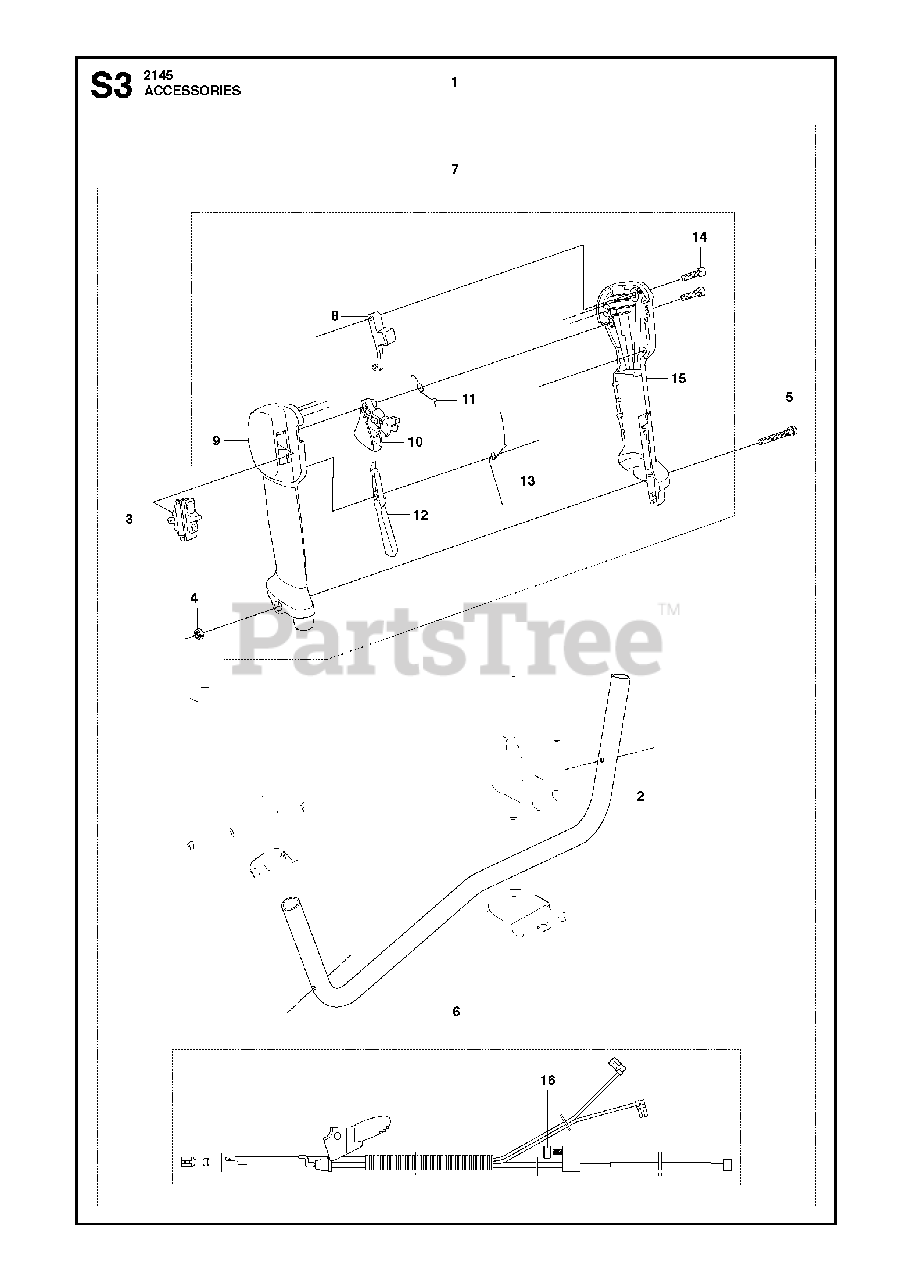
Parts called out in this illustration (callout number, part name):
2	HANDLE
4	NUT
5	%SCREW
6	WIRING ASSY
8	SWITCH
9	HANDLE HALF LEFT
10	TRIGGER
11	SPRING
12	TRIGGER SAFETY
13	SPRING
14	SCREW
16	SCREW
